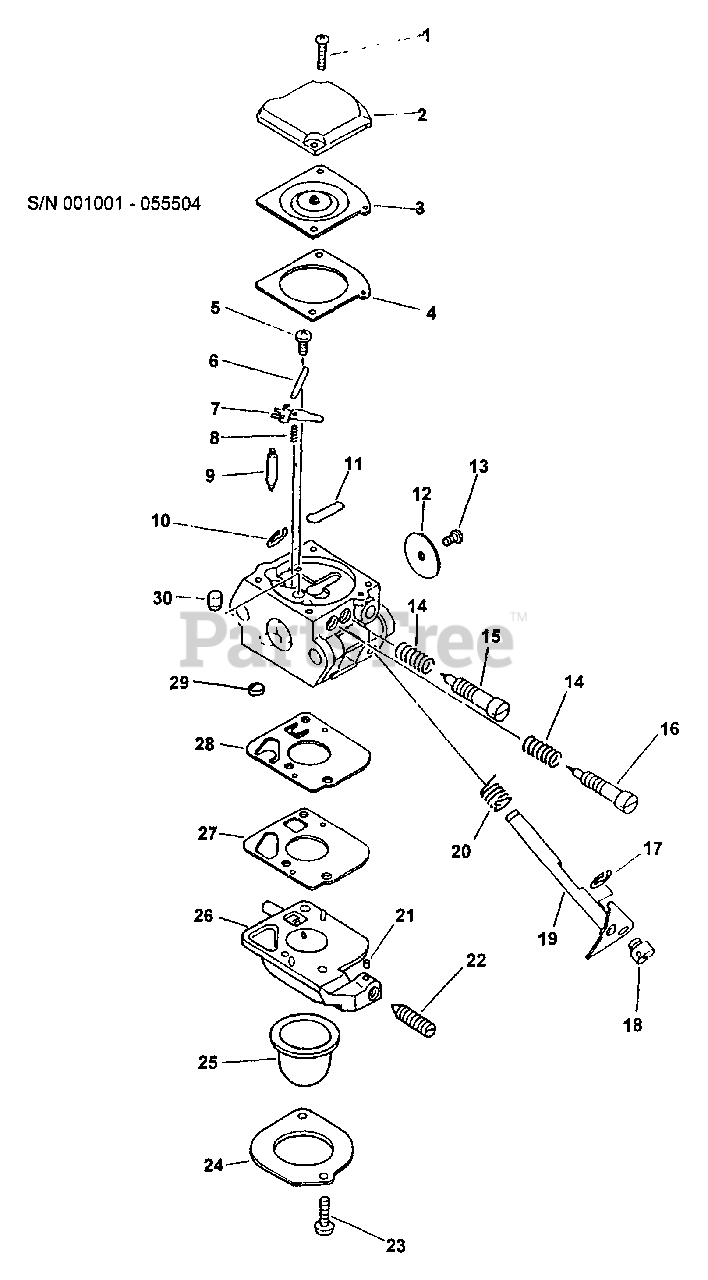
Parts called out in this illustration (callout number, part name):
2	COVER, DIAPHRAGM
3	DIAPHRAGM, METERING
4	GASKET, METERING
6	PIN
7	LEVER, METERING
8	SPRING, METERING LEVER
9	VALVE, NEEDLE
11	PLUG, WELCH
12	VALVE, THROTTLE
14	SPRING, NEEDLE
15	NEEDLE, LOW SPEED
16	NEEDLE, HIGH SPEED
19	SHAFT, THROTTLE
20	SPRING, THROTTLE RETURN
21	PIECE, FRICTION
22	SCREW, IDLE ADJUST
24	RETAINER
25	BULB, PURGE
26	BODY ASSY, PURGE
29	STRAINER
30	NOZZLE, CHECK VALVE
